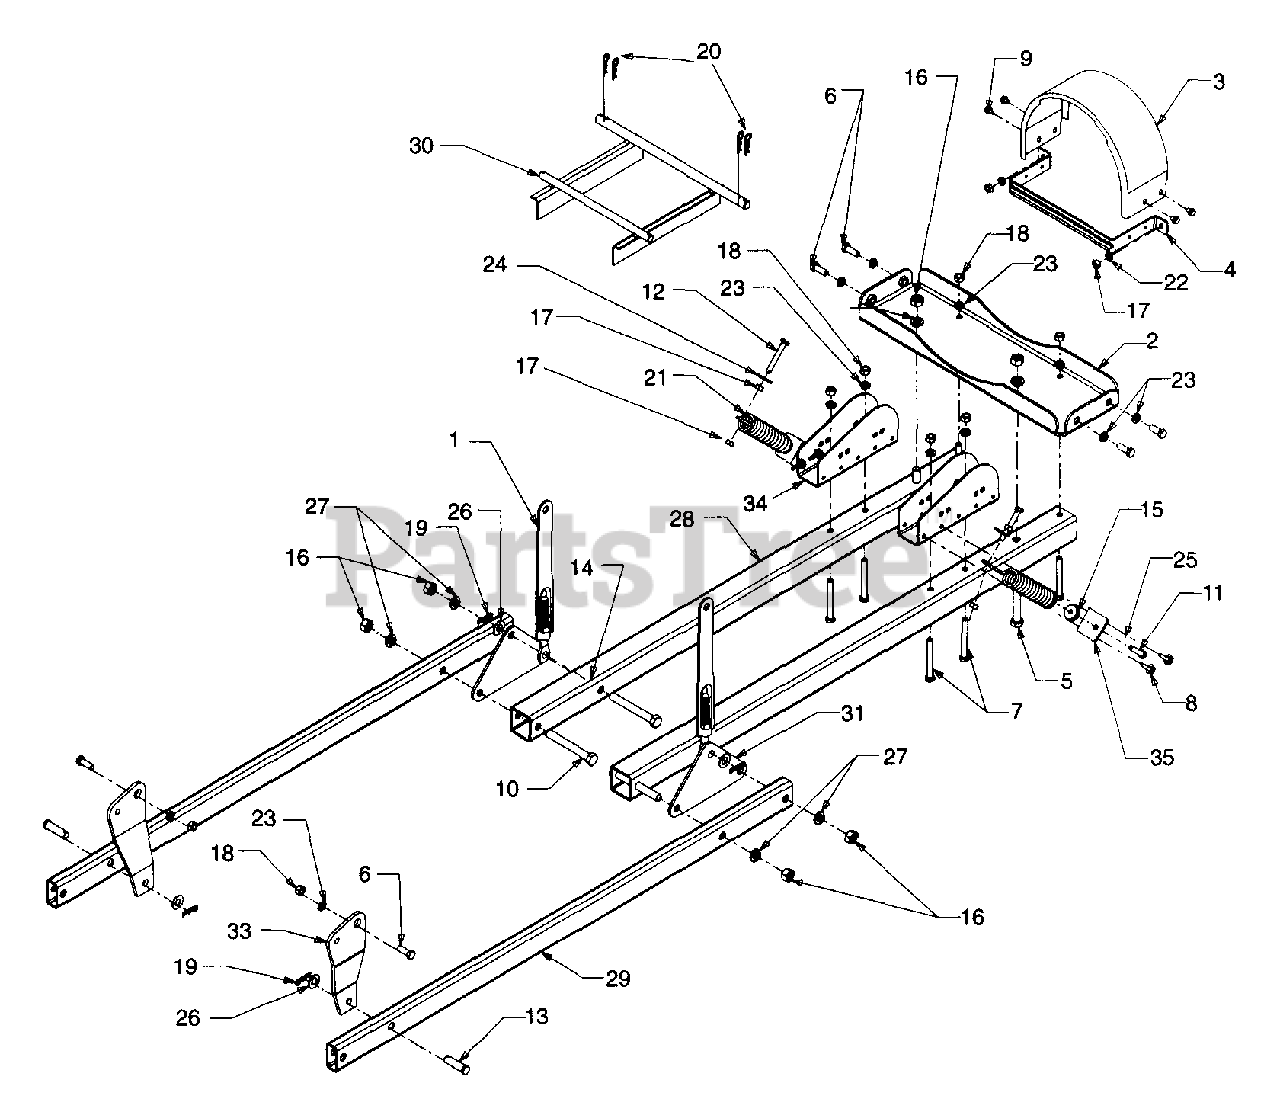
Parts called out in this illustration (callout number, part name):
1	Lift Asm:Deck Link:Front
6	HHCS:3/8-16:1.00:GR5:Std.
7	HHCS:3/8-16:3.00:GR8:Std.
8	Scr. TT 5/16-16:.50 HxIndWsh.
9	Scr:TT:1/4-20:.375:HxIndWsh.
10	HHCS:1/2-13:4.00:Gr5:Std.
11	HHCS:5/16-18:1.50:Gr5:Spec.
12	HHCS:5/16-18: 2.50:Gr5:Std.
13	Pin:Clv:.50 Dia. x 1.59 Lg.
14	Pin:Clv:.50 Dia. x .78 Lg.
15	Ins:Spring
16	Nut:1/2-13:GrA:Hx
17	Nut:5/16-18:GrB:Hx
18	Nut:3/8-16:GrB:Hx
19	Pin:Cot:Int .08 x 1.42
20	Pin:Cot:.125 x 1.75 Internal
21	Spr:Extn:1.25 O.D. x 7.25
22	Wash:Lock:5/16: Regular Duty
23	Wash:Lock:3/8:Regular Duty
24	Wash:Fl:.344 I.D. x 1.125 O.D.
25	Wash:Belvl:.340 I.D. X .872 O.D.
26	Wash:Fl:.510 X 1.00 X .060
27	Wash:Lock:1/2:Regular Duty
28	Tube:Lift:2.0 x 2.0 x 42.0 Lg.
31	Brkt:Lift Plate
32	Brkt:Hngr:RR LH
35	Brkt:Spr:Mt.
